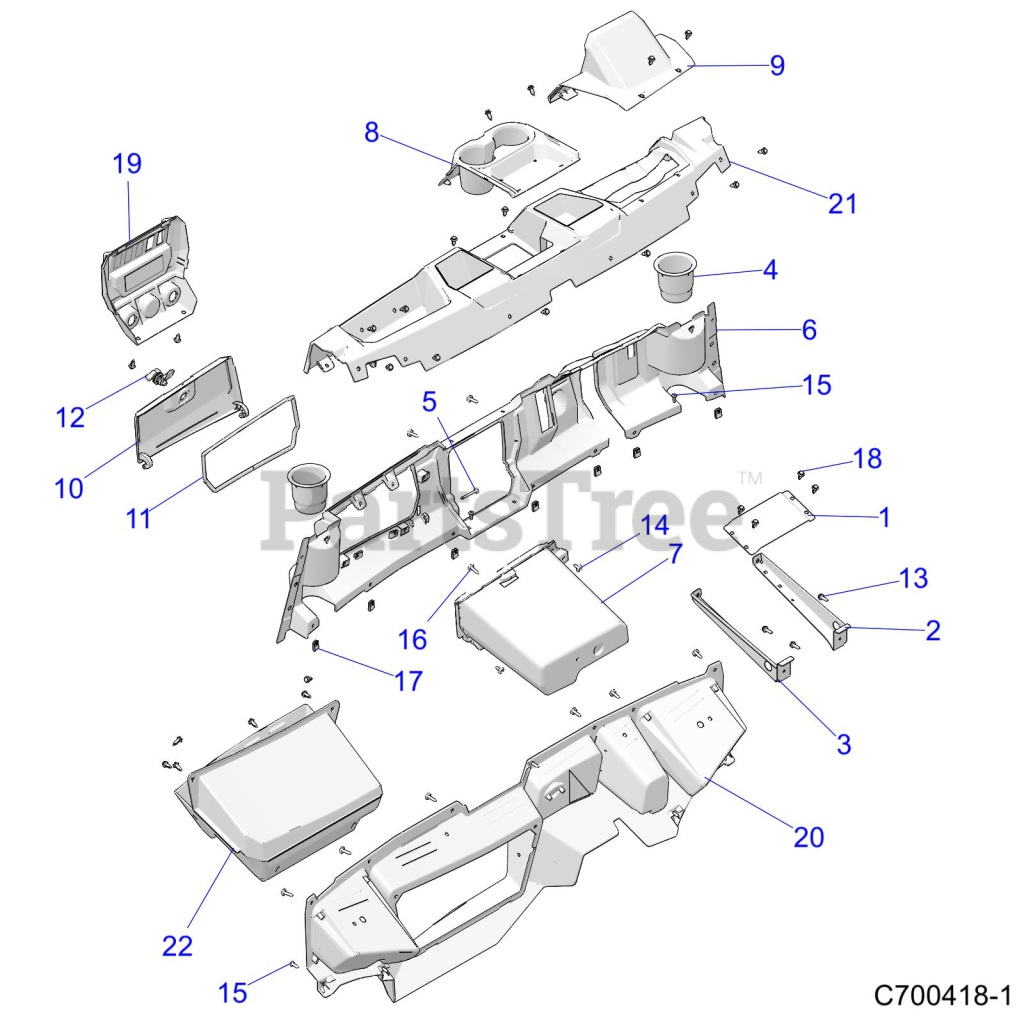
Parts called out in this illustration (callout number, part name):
1	BRKT-DRIP PLATE
2	BRKT-DASH,LH
3	BRKT-DASH,RH
4	HOLDER-CUP
5	PIN-HINGE,GLOVEBOX
6	DASH-MAIN,BLK
7	BIN-GLOVEBOX,BLK
8	DASH-CENTER TRAY,BLK
9	DASH-GAUGE BEZEL,BLK
10	COVER-BOX,GLOVE,BLK
11	SEAL-GLOVEBOX
12	LATCH-1/4 TURN,CAM
13	SCR-M6X1.0X20,HXHD,FLG,TDFM,BL
14	SCR-M6X1X16 TR/TX-M
15	SCR-TX TRUSS-#14X3/4,HI/LO ZBK
16	SCR-TXTH-M6X1.0X25 RIE
17	NUT-M6-1.0,U-TYPE (2.5-3.8)
18	RIVET-TUFLOK,.315-.325X.787 (5
19	DASH-CONTROLS,BLK
20	DASH-STORAGE,BLK
21	DASH-UPPER,BLK
22	BIN-LOWER,STORAGE,BLK
